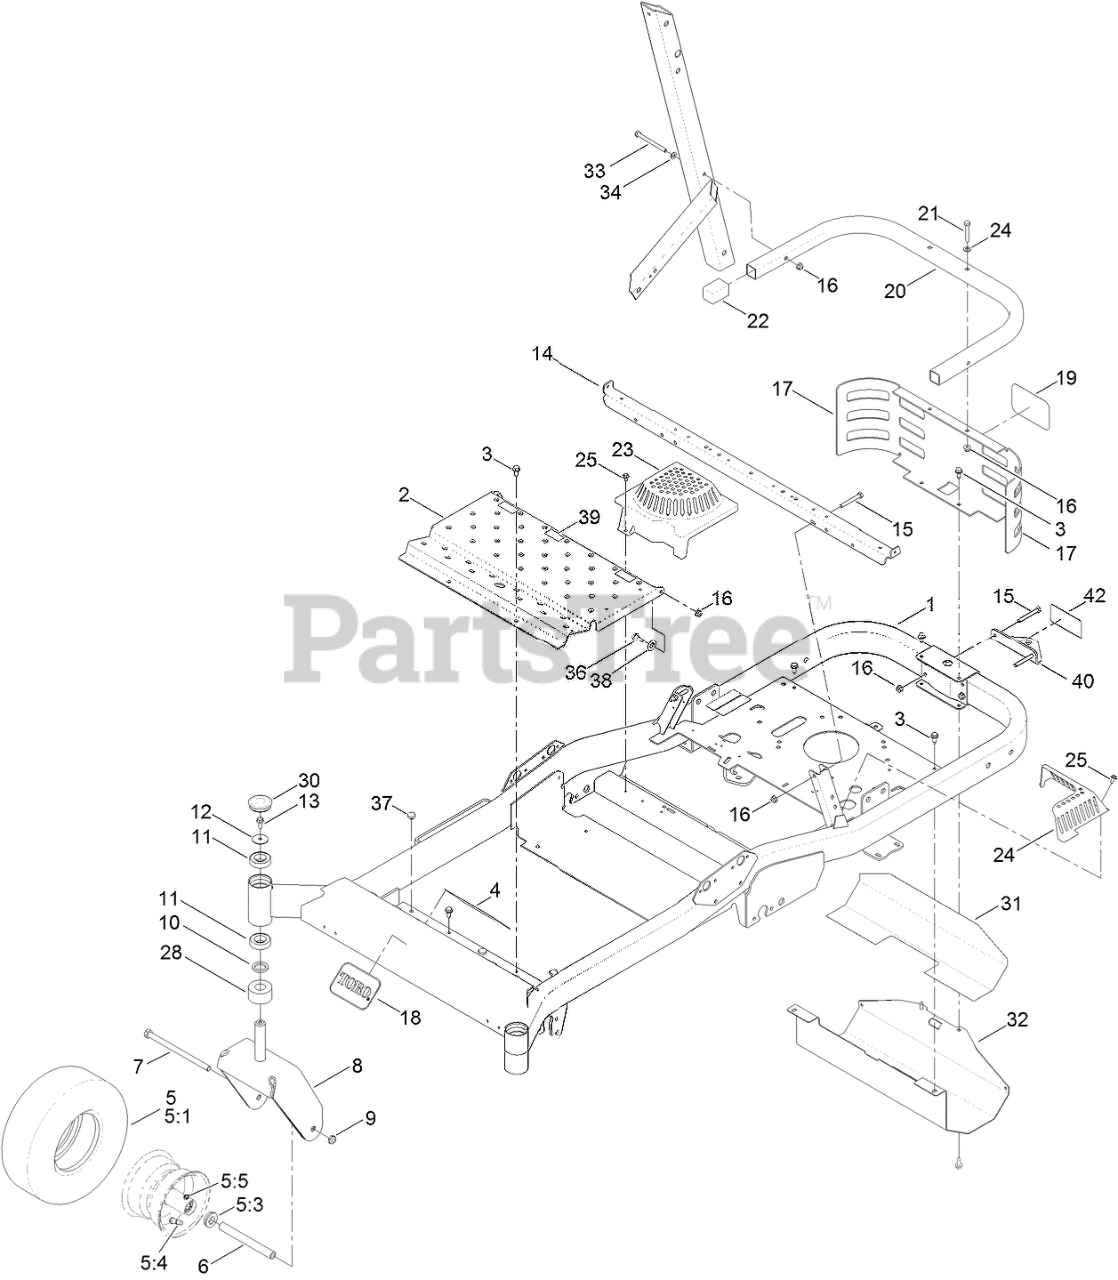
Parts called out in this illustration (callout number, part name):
1	FRAME ASM
2	PAN-FLOOR
3	SCREW-HWHTF
4	DECAL-DANGER
5	TIRE AND WHEEL ASM
5:1	TIRE-13 INCH SMOOTH
5:3	BUSHING-FLANGE
5:4	STEM-VALVE
5:5	FITTING-GREASE
6	SPANNER
7	SCREW-HH
8	NUT-LOCK, NI
9	FORK-CASTER
10	WASHER-THRUST
11	BEARING-BALL
12	WASHER-FLAT
13	SCREW-HHF
14	SUPPORT-SEAT
15	SCREW-HH
16	NUT-HF, NI
17	GUARD-REAR
18	DECAL
20	TUBE-GUARD
21	SCREW-HH
23	COVER-FAN, RH
24	COVER-FAN, LH
25	SCREW-HHFTF
28	SPACER-CASTER
30	CAP-GREASE
31	FOIL-HEAT SHIELD
32	SHIELD-HEAT
33	SCREW-HH
34	WASHER-PLAIN
36	SCREW-SHOULDER
37	BUMPER
38	WASHER-TEFLON
39	PAD-RUBBER
40	BRACKET-HITCH
